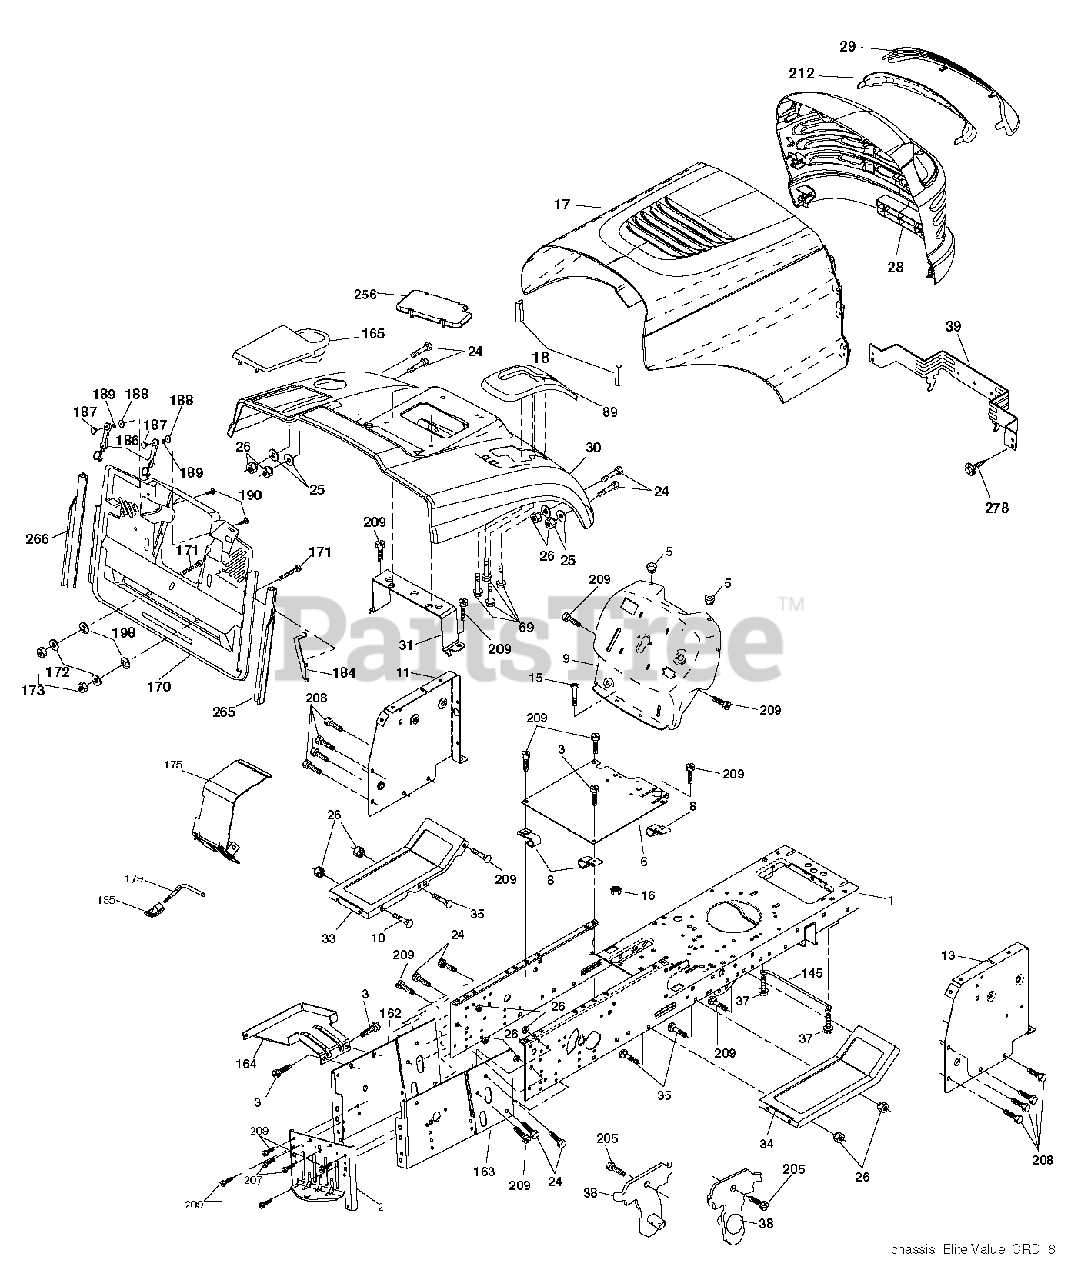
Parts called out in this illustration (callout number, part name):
1	CHASSIS
3	SCREW 3/8-16X3/4
5	BUMPER.RUBBER.HOOD
8	CLIP,INSULATOR
10	BOLT D
11	PANEL.DASH.LH.LTX
13	PANEL DASH RH
16	NUT
18	BUMPER.HOOD.LARGE.1.75"
24	BOLT
25	WASHER
26	NUT
31	BRACKET SUPPORT FENDER
35	BOLT
37	SCREW LT
39	BRACKET PIVOT
69	SCREW.HI-LO.CONSOLE
145	ROD.PIVOT.HOOD
164	SUPPORT
171	BOLT
172	WASHER
186	LATCH ASSY
187	WELDNUT
189	LOCKWASHER
190	SCREW
205	SCREW LT
207	SCREW, 5/16-18 X 1/2
208	SCREW 3/8-16X1/2
209	SCREW, 3/8-16X3/4
278	SCREW.#10 X 0.750.BOS THREAD
